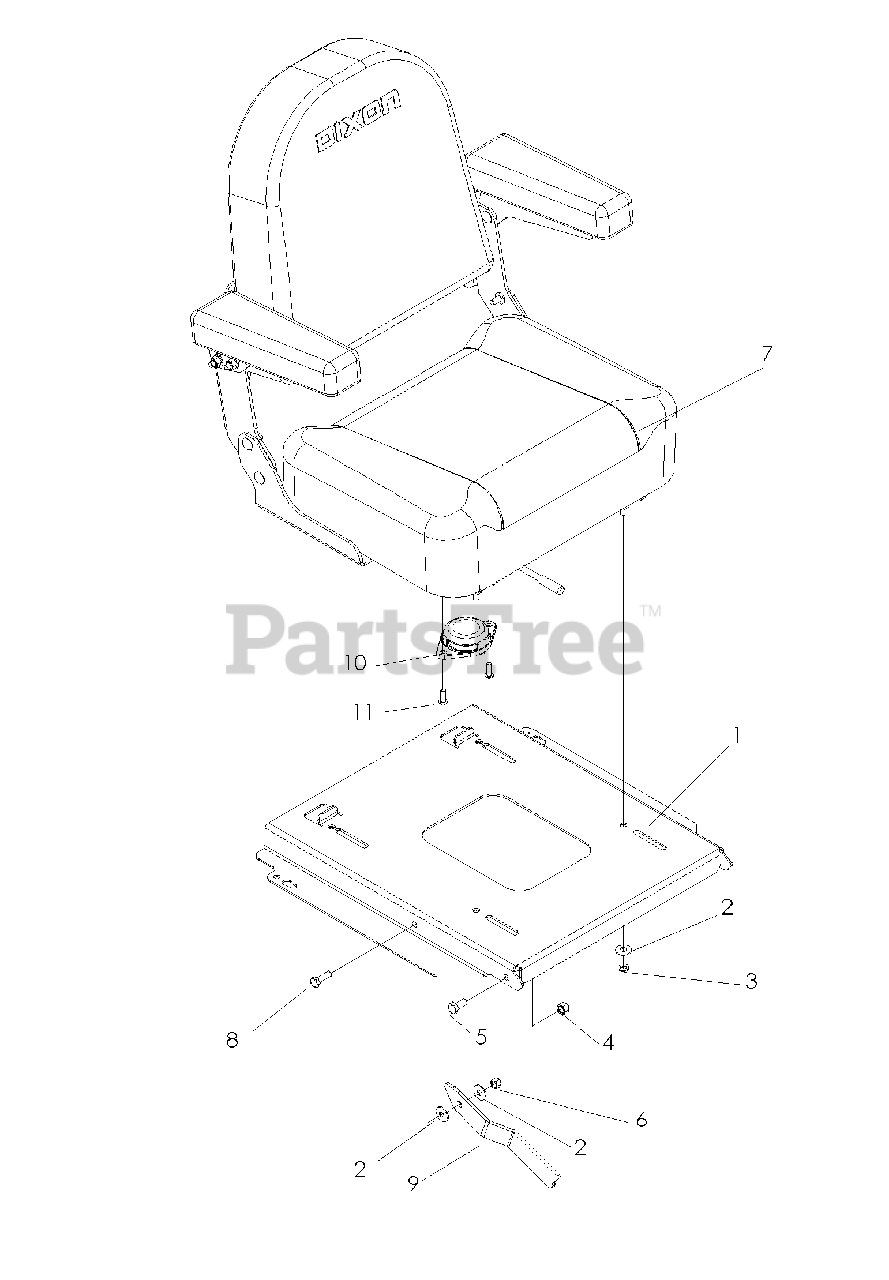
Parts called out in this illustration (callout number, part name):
1	PAN, SEAT, BLK
2	WASHER 5/16 FLAT
3	WASHER 5/16 LOCK
4	NUT 3/8-16 NYLOC
5	SCREW 3/8C X 3/4 HEX CAP
6	NUT 5/16 NYLOC
7	SEAT ASM W/SLIDE
8	HCS 5/16C X 1
9	ARM, PROP, SEAT
10	SEAT SWITCH MILSCO
11	SCR 1/4-20X3/4 SLTD RDHD GR2ZD
